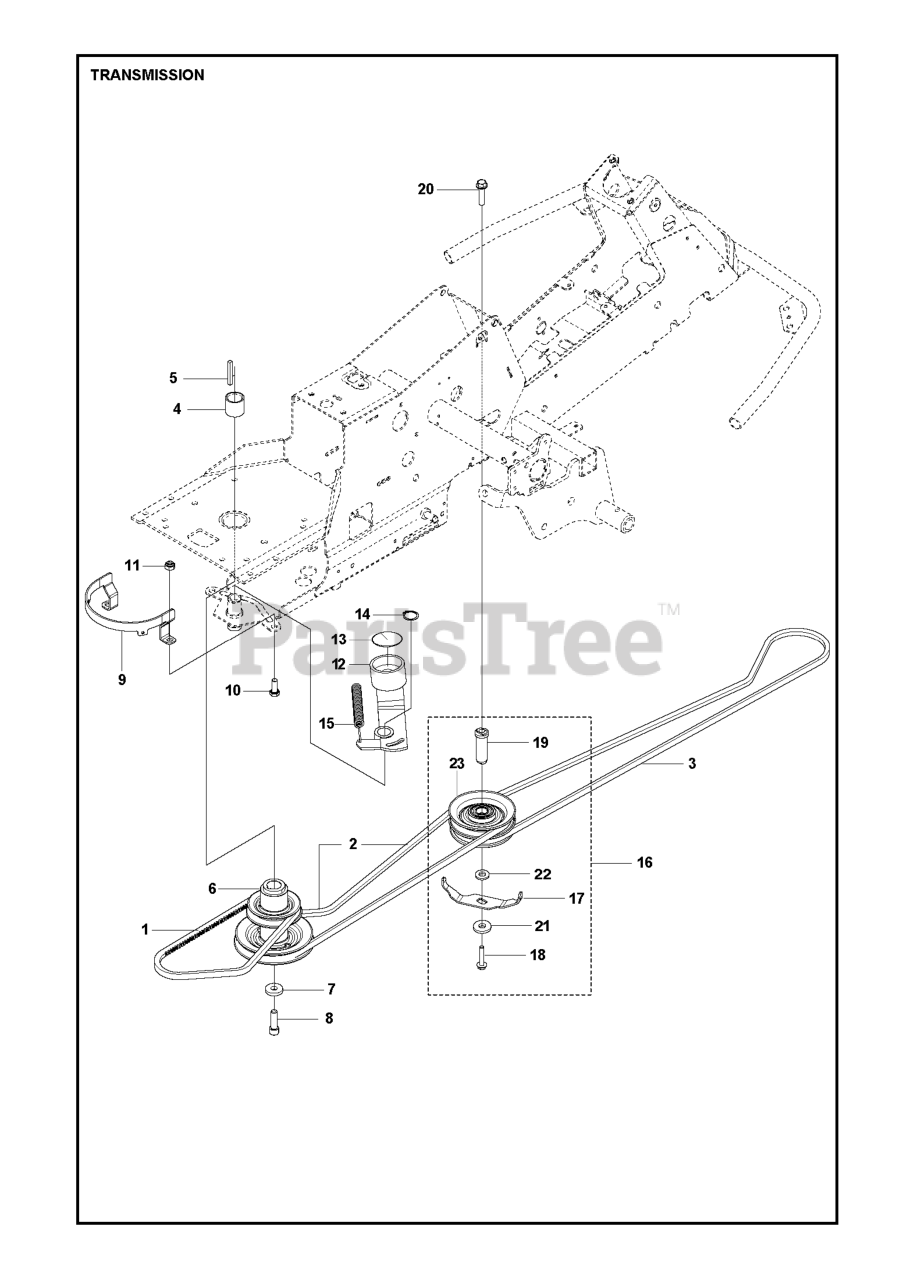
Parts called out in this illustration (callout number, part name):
10	Screw M10x25
11	NUT
14	RETAINING RING SGA 25
17	BELT GUIDE
23	PULLEY
